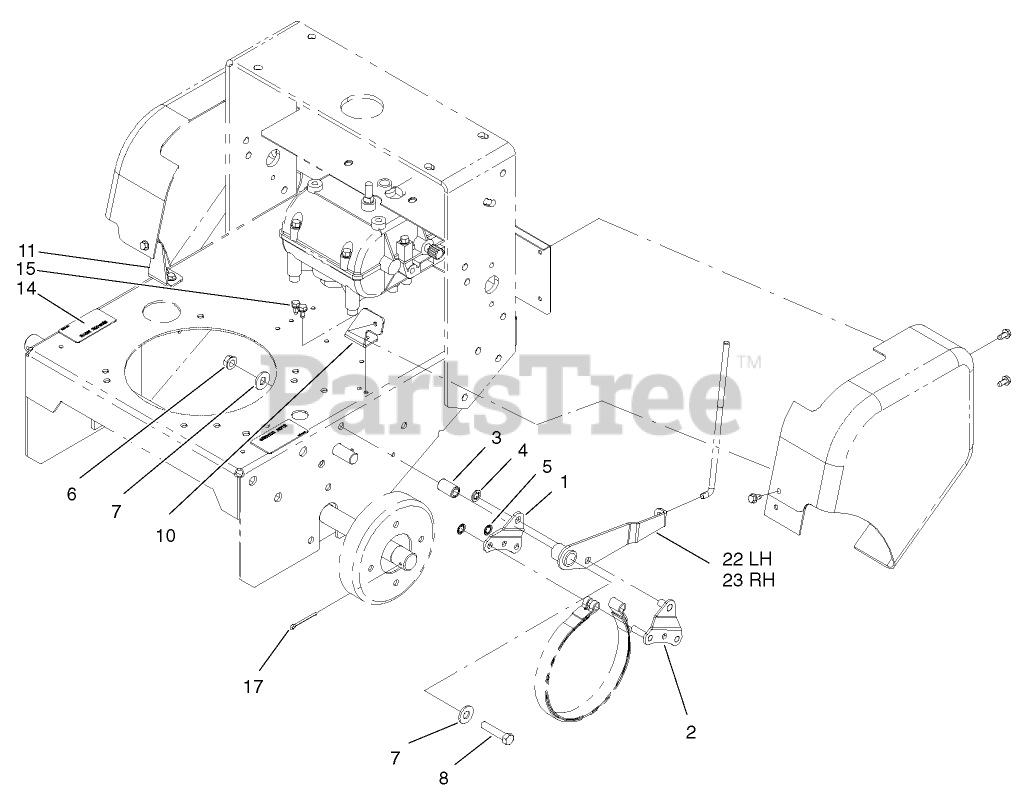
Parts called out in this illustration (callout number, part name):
4	RING-RETAINING, EXTERNAL
5	RING-RETAINING
6	NUT-FLANGE
7	WASHER-FLAT
8	SCREW-HH
15	SCREW
17	PIN-COTTER
